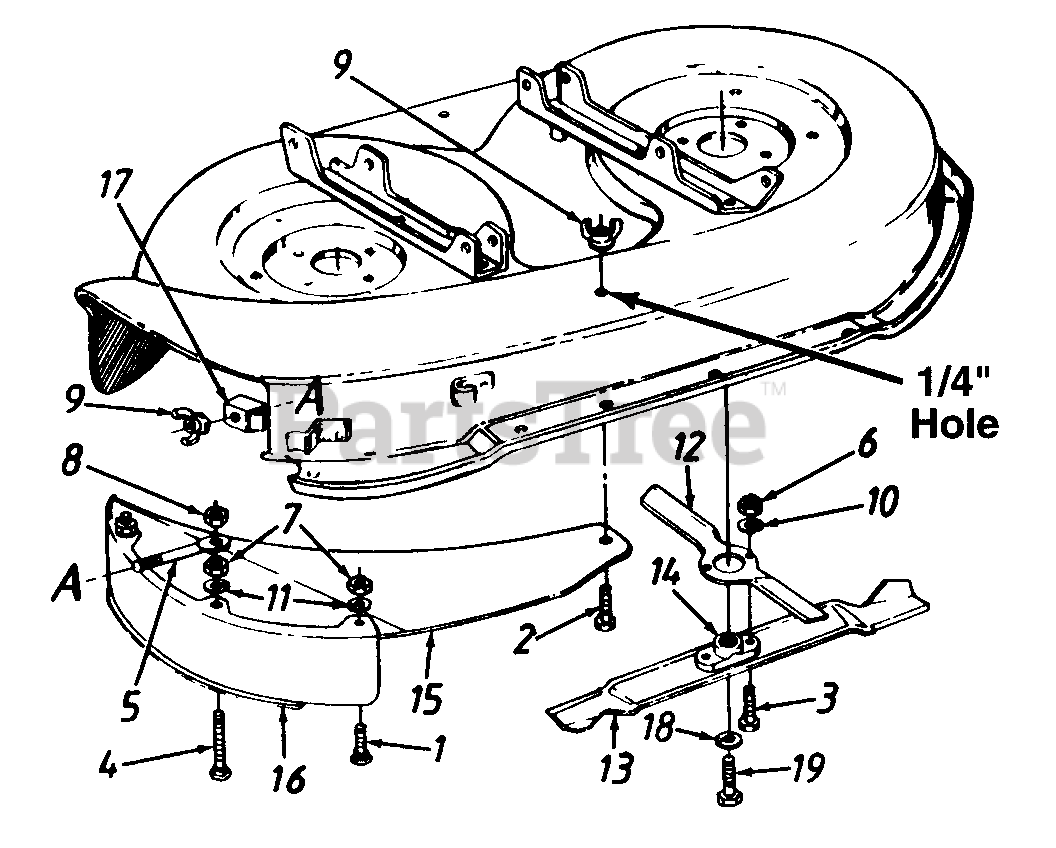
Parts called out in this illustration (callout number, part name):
1	Carriage Bolt 1/4-20 x 62" Lg.
2	Hex Bolt 1/4-20 x 1" Lg.
3	Hex Bolt 7/16-20 x 1.25" Lg. (Gr. 5)
4	Carriage Bolt 1/4-20 x 1" Lg.
5	Retaining Bolt
6	Hex Nut 7/16-20 Thd
7	Hex Nut 1/4-20 Thd.
8	Hex L-Nut 1/4-20 Thd.
9	Wing Nut
10	L-Wash. 7/16" I.D.
11	L-Wash. 1/4" I.D.
12	Mulching Blade 12.5"
13	Mulching Blade 19.38"
14	Blade Adapter
18	L-Wash. 3/8" I.D.
19	Hex Bolt 3/8-24 x 1" Lg. (Gr 8)
